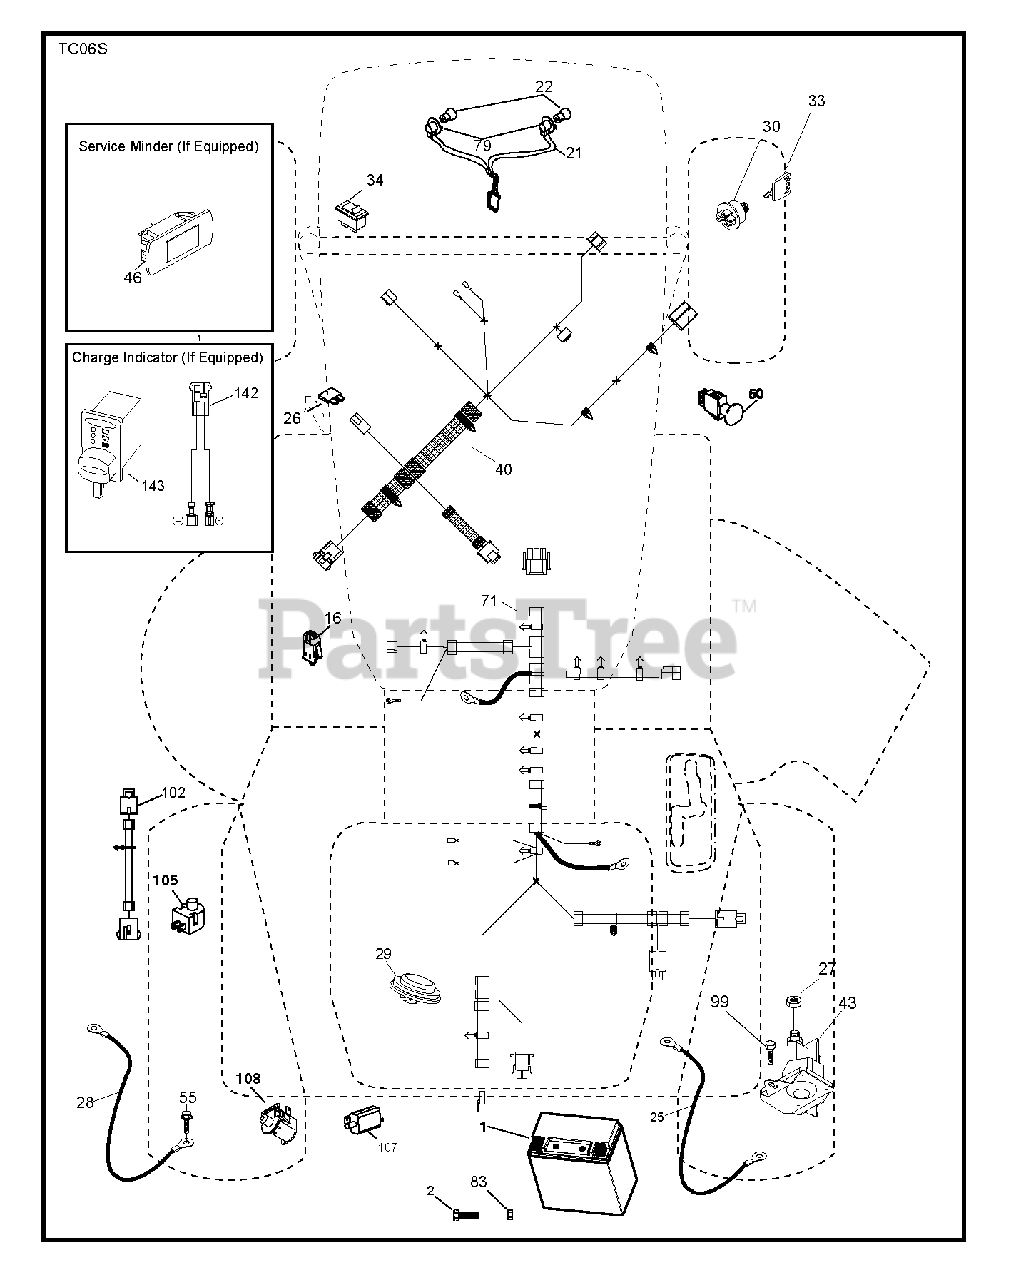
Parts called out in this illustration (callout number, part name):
1	BATTERY BATTERY 14AH 12V LEOC
2	SCREW.HEX.HEAD.CAP.M6 X1.12W
16	SWITCH INTERLOOK PUSH-IN
21	HARNESS.LIGHT W/4152J BULBS
25	CABLE CABLE.RED.20.8AWG.M6.CRD
26	FUSE 20AMP
27	NUT
28	CABLE CABLE.BLACK.20.8AWG.M6.C
29	SWITCH.SEAT.DELTA.OPC.
30	SWITCH.IGN.DELTA.W.LGH.ROS
33	KEY.CHAIN.BLISTER.PACK.GEN.INT
40	HARNESS.DASH.EL.SRD.CRD.RDY.ST
43	SOLENOID.W/BRASS.PLUNGER
46	GUAGE.SRVCMNDR.HRMTR.
50	RB PTO.SWITCH.8 TERMINAL.BLACK
55	SCREW 5/16"
71	HARNESS.CHASS.CRD.TEX.RDY.STRT
79	BULB HOLDER ASM.
83	NUT NUT SQUARE
99	SCREW
102	HARNESS ASSY
105	REVERSE SWITCH
107	.WITCH.FULL BAGGER.INDICATOR
108	SWITCH.SNAPMOUNT.NC
142	CHARGE.PORT.PIGTAIL HARNESS
143	CHARGE.PORT
